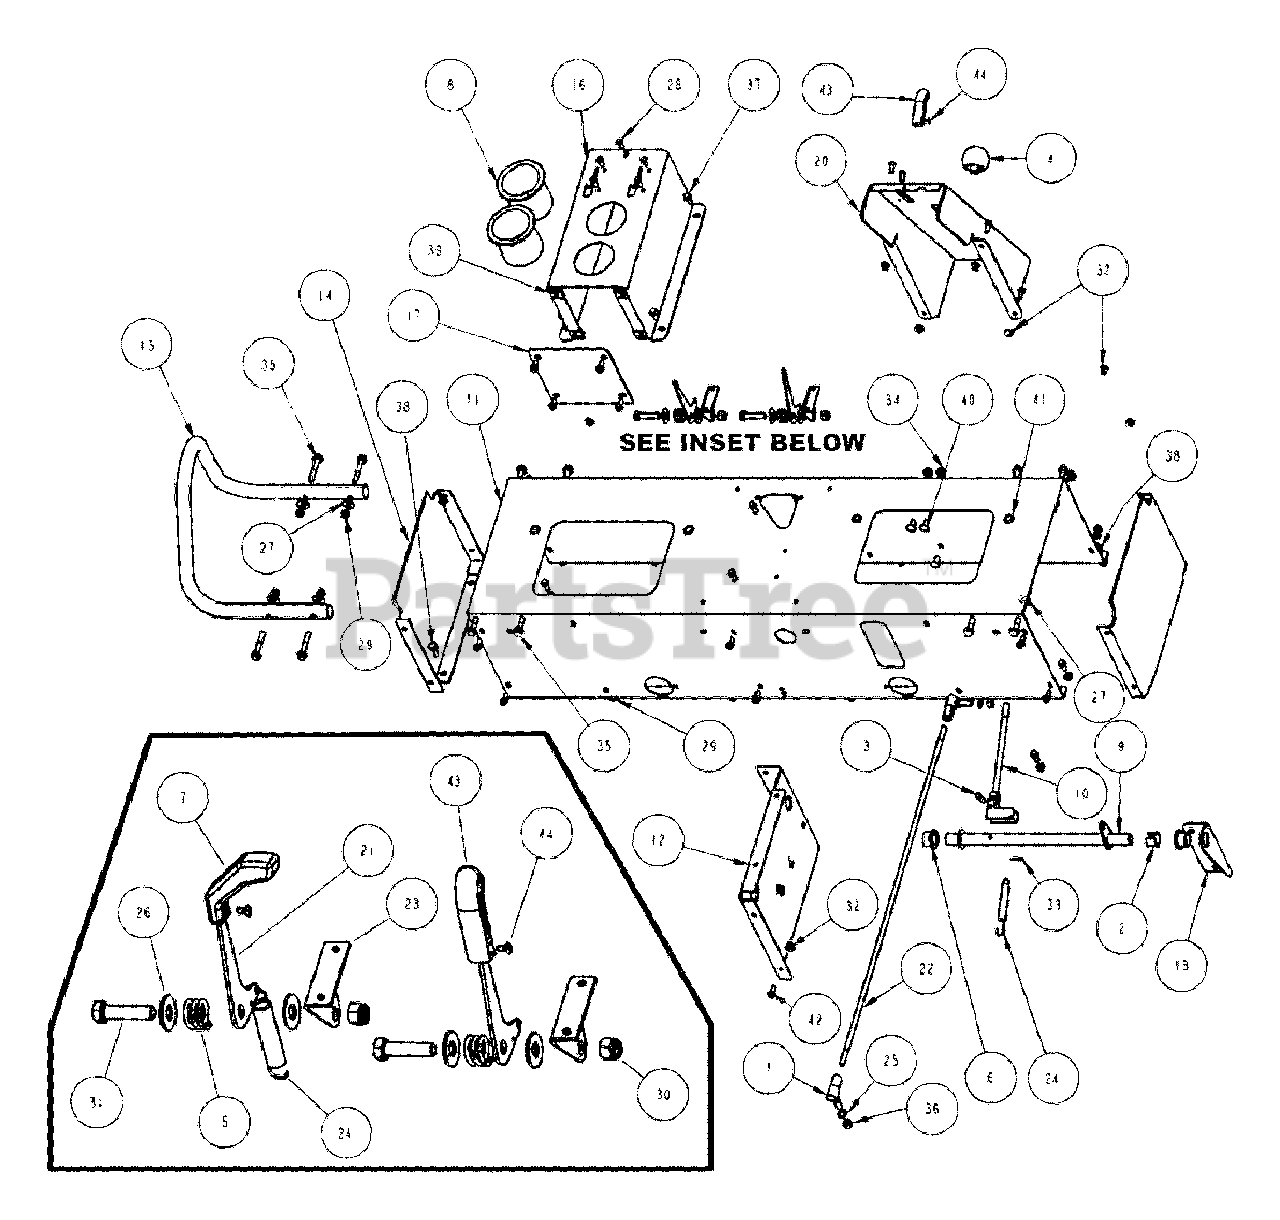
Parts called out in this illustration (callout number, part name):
1	BALL JOINT, 3/8-24 Thread
2	RING, REAR LIFT ARM
3	CLEVIS PIN, 1/4 X 1-1/8
4	BALL KNOB
5	FRICTION PACK SPRING
6	BEARING, .750 ID
7	HANDLE, RED PARK BRAKE
9	WELDMENT, TRANSMISSION SHIFTER
10	WELDMENT, HI-LO SHIFT LEVER
11	SEAT PEDESTAL
12	CENTER SUPPORT
13	BRKT., HI-LO CAM PIVOT
14	SIDE, SEAT PEDESTAL
15	HANDLE, SEAT PEDESTAL
16	CONSOLE
17	CONSOLE END CAP
20	DETENT BRACKET
21	LEVER, PARK BRAKE
22	ROD, LONG SHIFTER
23	BRKT., HANDLE SUPPORT
24	SPRING, EXTENSION
25	ITLW, 3/8
26	WASHER, 1/4 X 1 X .065
27	FLW .375 X .88 X .083
28	PHST, 1/4-20 X 5/8 TORX
29	HEX NYLON INSERT NUT 5/16-18 YZ
30	HNYL,3/8-16, YZ
31	HHCS 3/8-16X 1 1/2 GR5 YZ
32	HFLN, 1/4-20
33	COTTER PIN, 3/32 X 3/4 YZ
34	FLN 5/16-18 YZ
35	HFLB 5/16-18 X 2"
36	HN, 3/8-24 YZ
37	HFLS, 1/4-20 X 5/8
38	HFLB, 5/16-18 x 7/8 - YZ
39	U-NUT, 1/4-20
40	RHSSNB, 5/16-18 x 5/8 - YZ
41	RIV-NUT, 5/16-18 HEX
42	HFLCS, 1/4-20 X 1/2"
43	KNOB, THROTTLE CONTROL
44	RIVET, Plastic Snap
